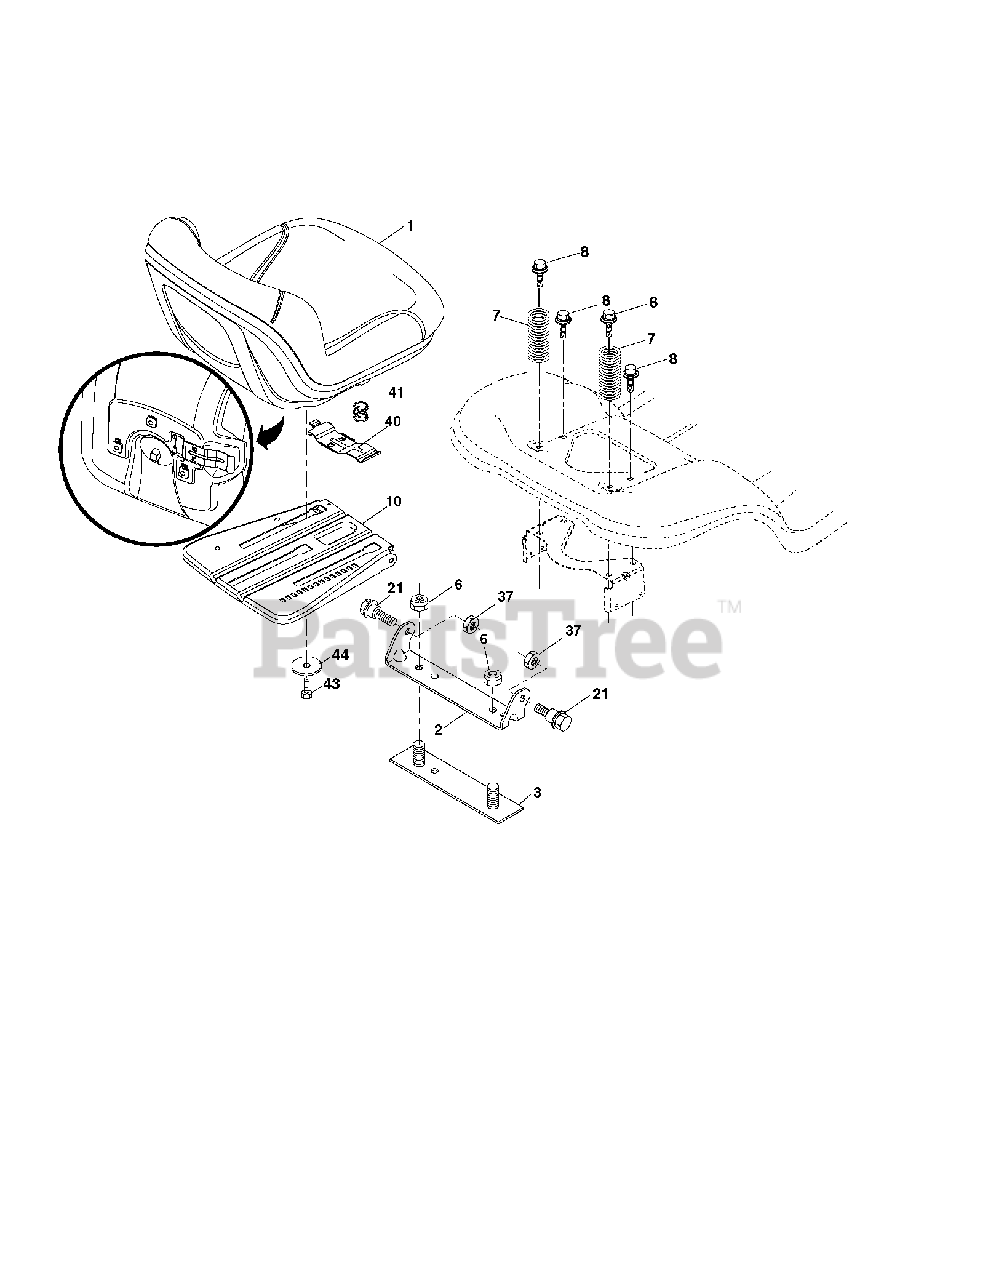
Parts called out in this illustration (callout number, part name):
1	SEAT.TP150.BLK.PPRO.KB/SL
2	BRKT.PIVOT.FENDER
6	NUT
7	SPRING COMPRESSION
8	BOLT, 5/16-18 X 1 3/4
10	PAN.ASM.SEAT.3PT
21	BOLT.SHOULDER.5/16-18
37	NUT.71038.31-18.HEX.NYLOCK
40	HANDLE.SLIDE.SEAT.TEX.BLACK
41	SPRING.LATCH.SEAT.TEX
44	WASHER 13/32 X 2-3/8 X 12GA
